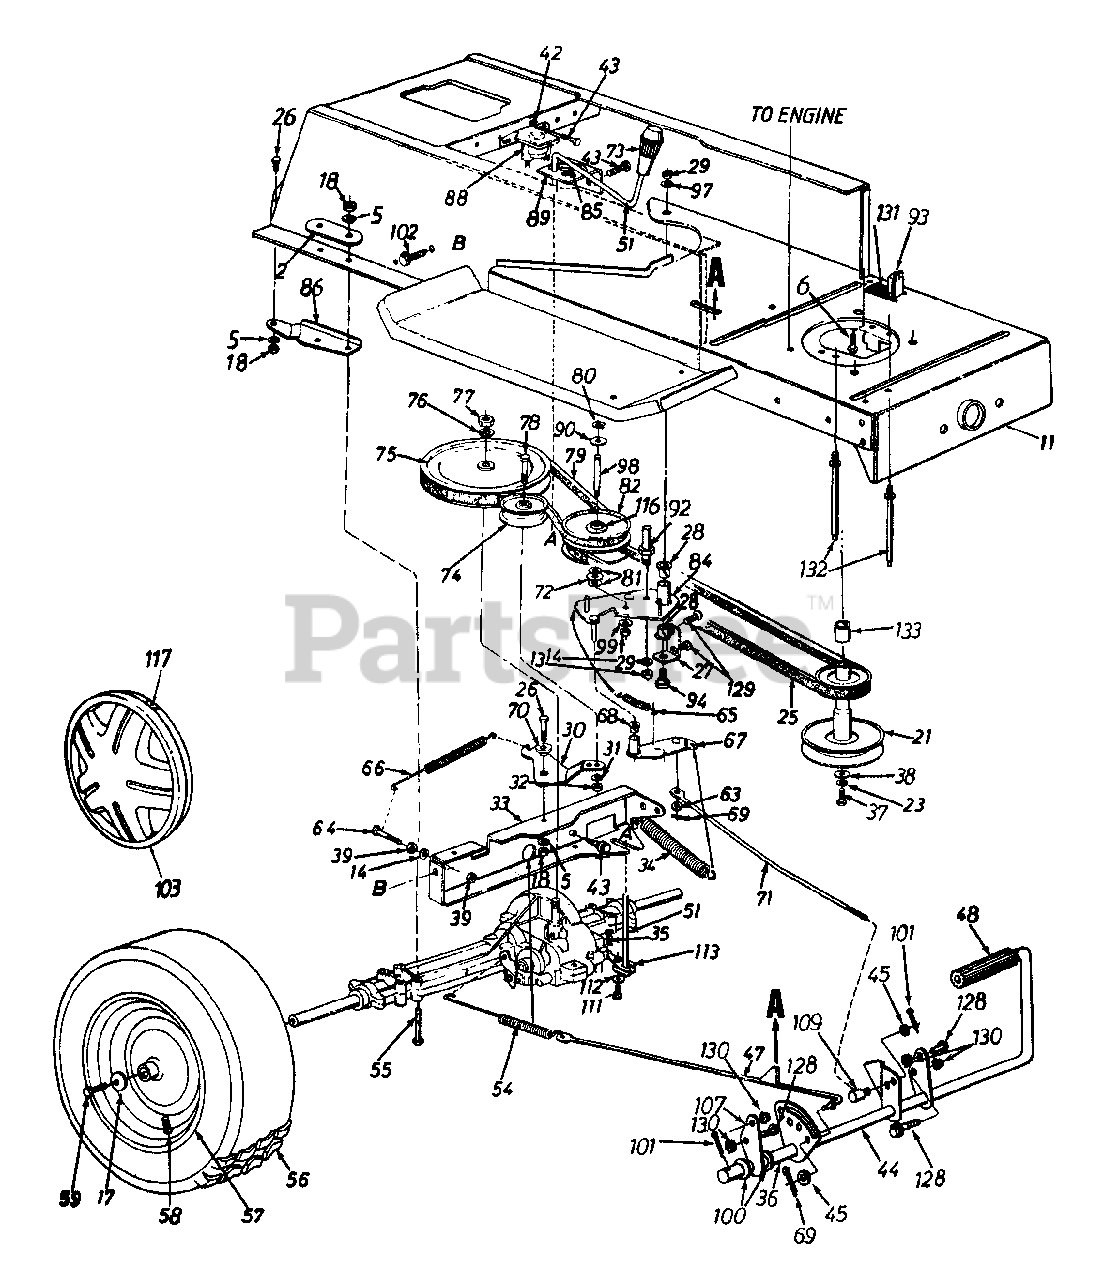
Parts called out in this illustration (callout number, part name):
5	L-Wash. 5/16" I.D.
13	Hex Nut 1/4-20 Thd.
14	L-Wash. 1/4" I.D.
17	Bell-Wash. .345" I.D. x .88"
18	Hex Nut 5/16-18 Thd.
21	Engine Pulley
23	L-Wash. 7/16" I.D.
25	Variable-Speed Belt
26	Hex Bolt 5/16-18 x .75" Lg.
27	Bearing Shaft Bracket Ass'y.
28	Flanged Nyliner Brg. 5/8" I.D. x .88" Lg.
29	Hex Nut 3/8-24 Thd.
31	L-Wash. 3/8" I.D.
32	Hex Nut 3/8-24 Thd.
35	Inter. Cotter Pin
36	Spacer .63" I.D.
37	Hex Bolt 7/16-20 x 1.5" Lg.
38	Shld. Spacer .445" I.D.
39	Hex Nut 1/4-28 Thd.
40	Hex AB-Tap Scr. 1/4" x .62" Lg.
41	Belt Guard Pin
42	Ext. L-Wash. 1/4" I.D.
43	Hex Wash. Hd. S-Tap Scr. 1/4-20 x .50"
47	Brake Rod Ass'y.
48	Foot Pad
51	Shift Lever Ass'y.
53	Ext. Spring .38" O.D. x 2.5"
54	Ext. Spring 7.33" Lg.
55	Hex Bolt 5/16-18 x 3.5" Lg.
58	Air Valve
59	Hex Bolt 5/16-24 x .75" Lg.
61	Brake Return Spring Anchor
63	Fl-Wash. .34" I.D. x .68" O.D.
64	Hex Bolt 1/4-28 x 1.25" Lg.
65	Ext. Spring
66	Ext. Spring .62" O.D. x 6.12"
68	Flanged Bearing
69	Cotter Pin 3/32" Dia.
70	Shoulder Spacer .27" Lg.
71	Speed Control Link
72	Truss Bearing .56 Dia. x 1.25"
73	Shift Knob
74	Fl-Idler Pulley 3.25" x .75"
76	Bell-Wash. .56" I.D. x 1.125"
77	Hex Jam Nut 5/16-18 Thd.
78	Hex Bolt 3/8-24 x 1.75" Lg.
79	Variable Speed Belt
80	Snap Ring .56" Dia.
82	Variable Speed Pulley Ass'y. 5" O.D.
90	Teflon Washer .565" I.D.
92	Belt Keeper 3" Lg.
93	Safety Switch (Clutch)
94	Shld. Bolt 3/8-24 x 3.12" Lg.
97	Bell-Wash. .38" I.D. x .88"
98	Shaft .56" Dia. x 3.875" Lg.
99	Bell-Wash. .39" I.D. x 1.12"
100	Fl-Wash. .64" I.D. x .94"
101	Cotter Pin 1/8" Dia. x 1.25"
102	Hex Wash. Hd. Scr. 5/16-18 x .62" Lg.
111	Hex Bolt 1/4-28 x .50" Lg.
112	Bell-Wash. .265" I.D. x .75"
113	Shift Lever Link Ass'y.
115	Fl-Wash. .385" I.D. x .62"
116	Needle Brgs.
117	Spring Clip
119	Hex Bolt 3/8-16 x 1.25" Lg.
120	Fl-Idler w/Flanges 2.75" O.D.
121	Fl-Wash. .39" I.D. x 1.12" O.D.
122	Hex Nut 3/8-16 Thd.
128	Hex Wash. TT-Tap Scr. 5/16-18 x .75" Lg.
129	Hex Wash. AB-Tap Scr. 5/16-18 x .75" Lg.
130	Hex Sems Nut 5/16-18 Thd.
131	Spring Switch
132	Belt Guard Pin
